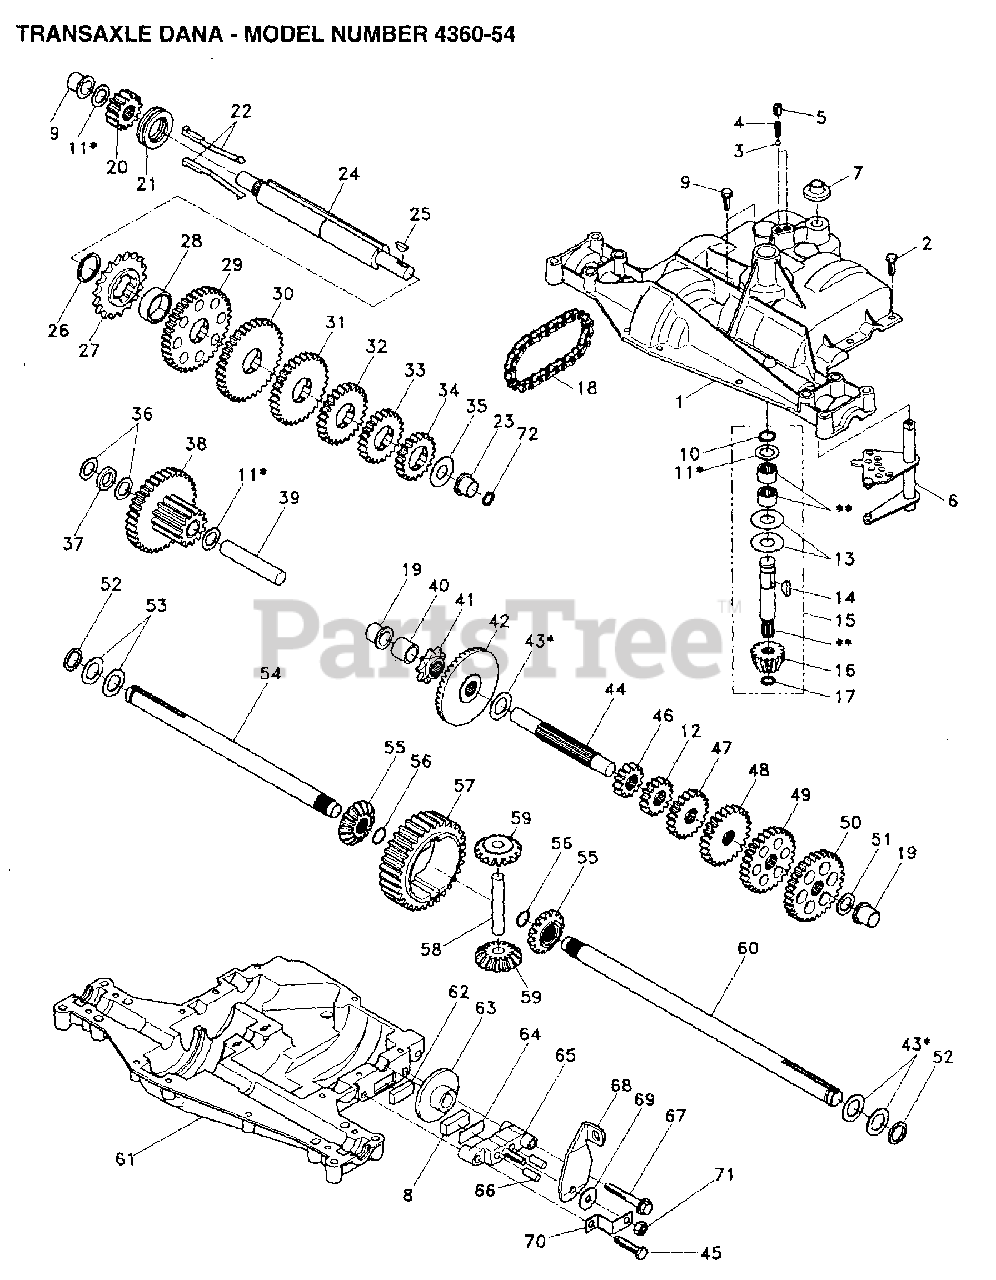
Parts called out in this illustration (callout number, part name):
1	HOUSING UPPER
3	BALL, DETENT
4	SPRING, DETENT
5	SCREW, SET
6	KIT, SHIFTER ASSEMBLY
7	BOOT, SHIFTER
8	PUCK, FRICTION
9	SCREW TAPPING WITH SEALER
10	RING RETAINING
11	ASSY, KIT, SHIM .625 SHAFT
12	GEAR SPUR, 15 TEETH
13	WASHER, PLAIN .632 X 1.38 X .046
14	KEY WOODRUFF #9
15	ASSY KIT INPUT SHAFT
16	PINION BEVEL 14 TEETH
17	RING, RETAINING
18	CHAIN, 24 PITCHES
19	BEARING, FLANGE
21	COLLAR, CLUTCH
22	ASSY, KIT, CLUTCH KEYS
23	BEARING FL
24	SHAFT INTERMEDIATE
25	KEY, WOODRUFF, #61
26	RING, RETAINING
27	SPROCKET, 18 TEETH
29	GEAR, SPUR, 37 TEETH
30	GEAR, SPUR, 35 TEETH
31	GEAR, SPUR, 30 TEETH
32	GEAR, SPUR, 25 TEETH
33	GEAR, SPUR, 22 TEETH
34	GEAR, SPUR, 19 TEETH
35	WASHER, PLAIN .640 X 1.37 X .061
36	WASHER, PLAIN .632 X 1.00 X .026
37	SPACER .630 X 1.00 X .169
38	ASSY GEAR COMB 12&35 TEETH
39	SHAFT, IDLER
40	SPACER .635 X .875 X .755
41	SPROCKET, 9 TEETH
42	GEAR, BEVEL, 42 TEETH
43	ASSY, KIT, SHIM .750 SHAFT
44	SHAFT, DRIVE
45	SCREW TAPPING
46	GEAR, SPUR, 12 TEETH
47	GEAR, SPUR, 20 TEETH
48	GEAR, SPUR, 25 TEETH
49	GEAR, SPUR, 28 TEETH
50	GEAR, SPUR, 31 TEETH
51	WASHER, PLAIN .632 X 1.00 X .060
52	WASHER, NEOPRENE
53	WASHER, PLAIN .758 X 1.25 X .031
54	AXLE LEFT HAND
55	GEAR MITER 15 TEETH
56	RING, RETAINING
57	GEAR, SPUR, 32 TEETH
58	SHAFT, CROSS
59	GEAR, MITER, 15 TEETH
60	AXLE, R.H.
61	HOUSING LOWER
62	PUCK, FRICTION
63	DISC, BRAKE
65	JAW, BRAKE
66	PIN, DOWEL
67	SCREW, SELF-TAPPING
68	LEVER ACTUATING
69	WASHER, PLAIN .321 X 1.00 X .055
70	BRACKET, ANTI-ROTATION
71	LOCKNUT 5/16-24
72	SQUARE RING
